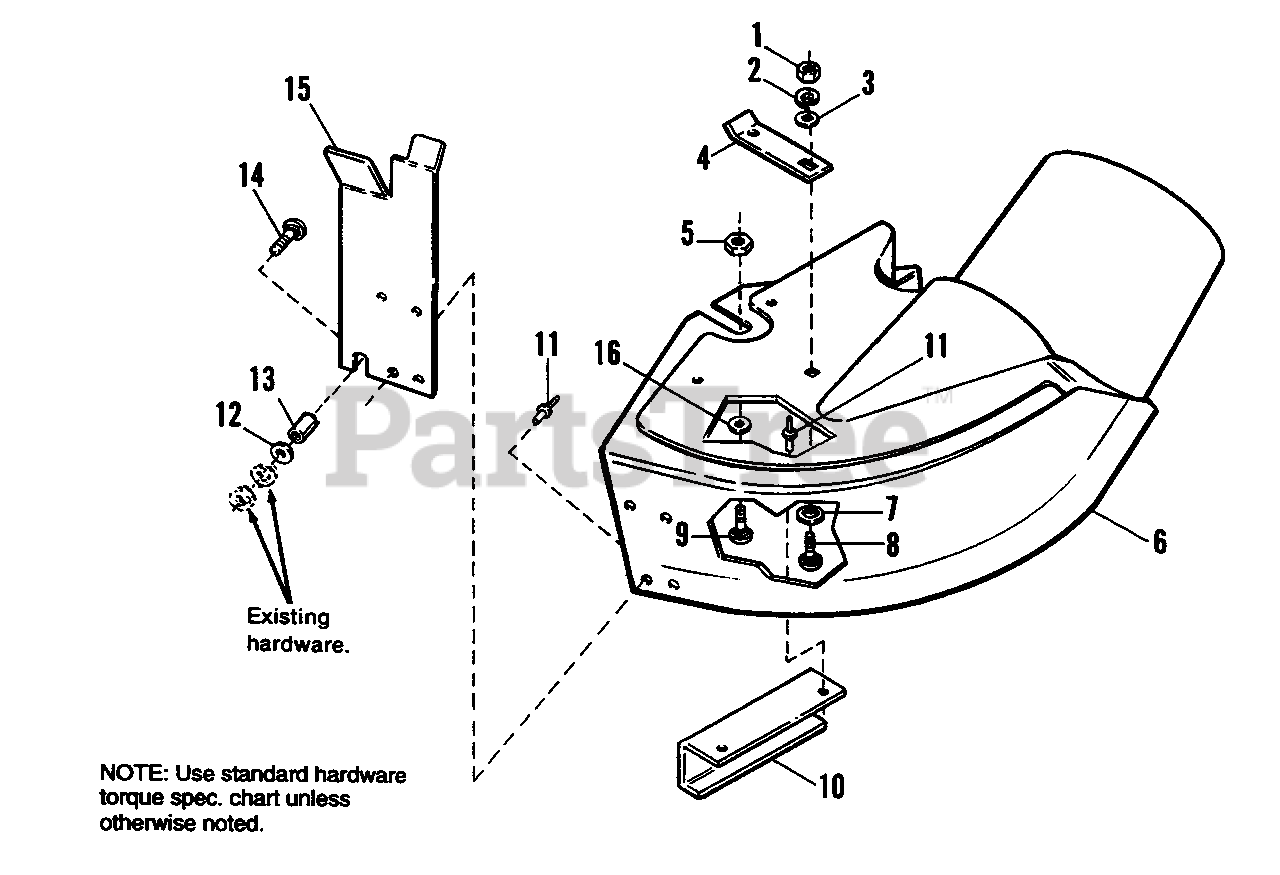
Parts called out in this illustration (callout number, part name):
1	NUT, Hex, 5/16-18 UNC,2B
2	LOCKWASHER, 5/16 Helical Spring
3	WASHER, Plain, 3/8 x 7/8
4	LATCH, Spring
5	NUT, Hex, Centerlock, Jam, 3/8-16 UNC
6	ADAPTOR ASSY.
7	WASHER, Plain, 7/16 x 1
8	BOLT, Rd. Hd., 5/16-18 UNC x 1
9	BOLT, Rd. Hd., 3/8-16 UNC x 7/8
10	ADAPTOR, Hold Down
11	RIVET, Oval Hd., 3/16 x 5/16
12	WASHER, Plain, 3/8 x 1-1/4 x 1/8
14	BOLT, Rd. Hd., 3/8-16 UNC x 1-1/4
15	DEFLECTOR BRACE ASSY.
16	WASHER Plain. 1/2 x 7/8
